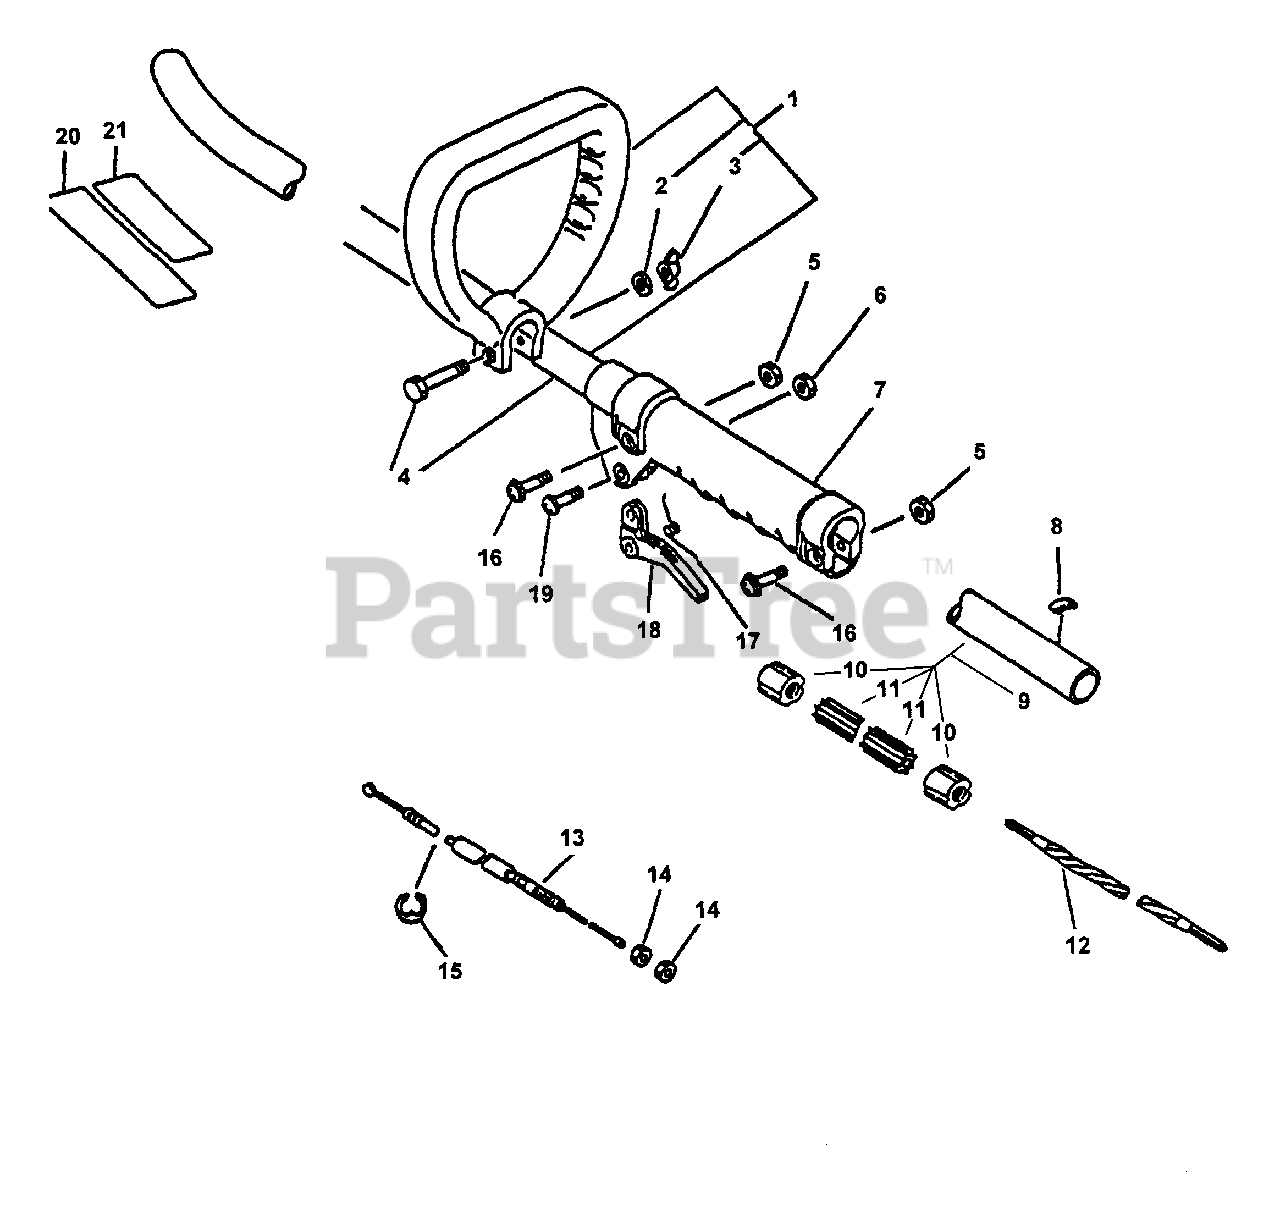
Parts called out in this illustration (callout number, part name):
1	HANDLE ASSY
2	WASHER - 6
2	WASHER - 1/4"
3	WINGNUT - 6
3	WINGNUT - 1/4-20
4	BOLT - 6X40
4	BOLT - 1/4-20 X 1-1/2"
6	LOCKNUT - 5
7	GRIP, HANDLE
8	LABEL - ALIGNMENT
9	MAIN PIPE ASSY
11	LINER - FLEXIBLE
12	DRIVESHAFT - FLEXIBLE
13	CABLE, THROTTLE
15	RING, RETAINING - 5
16	SCREW - 5X25
17	SPRING, TRIGGER
18	TRIGGER, THROTTLE
19	SCREW - 5X30
20	LABEL - CAUTION
21	LABEL - CAUTION
